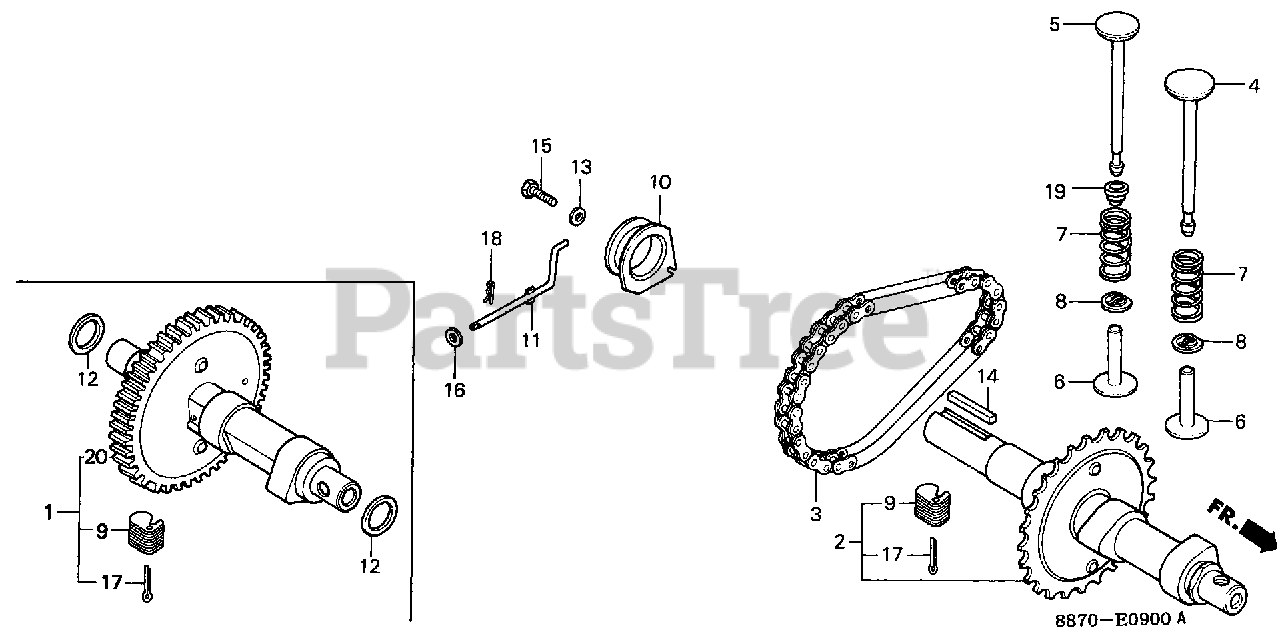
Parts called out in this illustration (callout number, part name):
1	CAMSHAFT ASSY.
4	VALVE, IN.
5	VALVE, EX.
6	LIFTER, VALVE (34.39)
6	LIFTER, VALVE (34.66)
7	SPRING, VALVE
8	RETAINER, VALVE SPRING
9	WEIGHT, GOVERNOR
10	SLIDER, GOVERNOR
11	SHAFT, GOVERNOR ARM
12	WASHER, THRUST (18MM)
16	WASHER, PLAIN (5MM)
17	PIN, SPLIT (3.0X25)
17	PIN, SPLIT (3.0X45)
18	PIN, LOCK (8MM)
